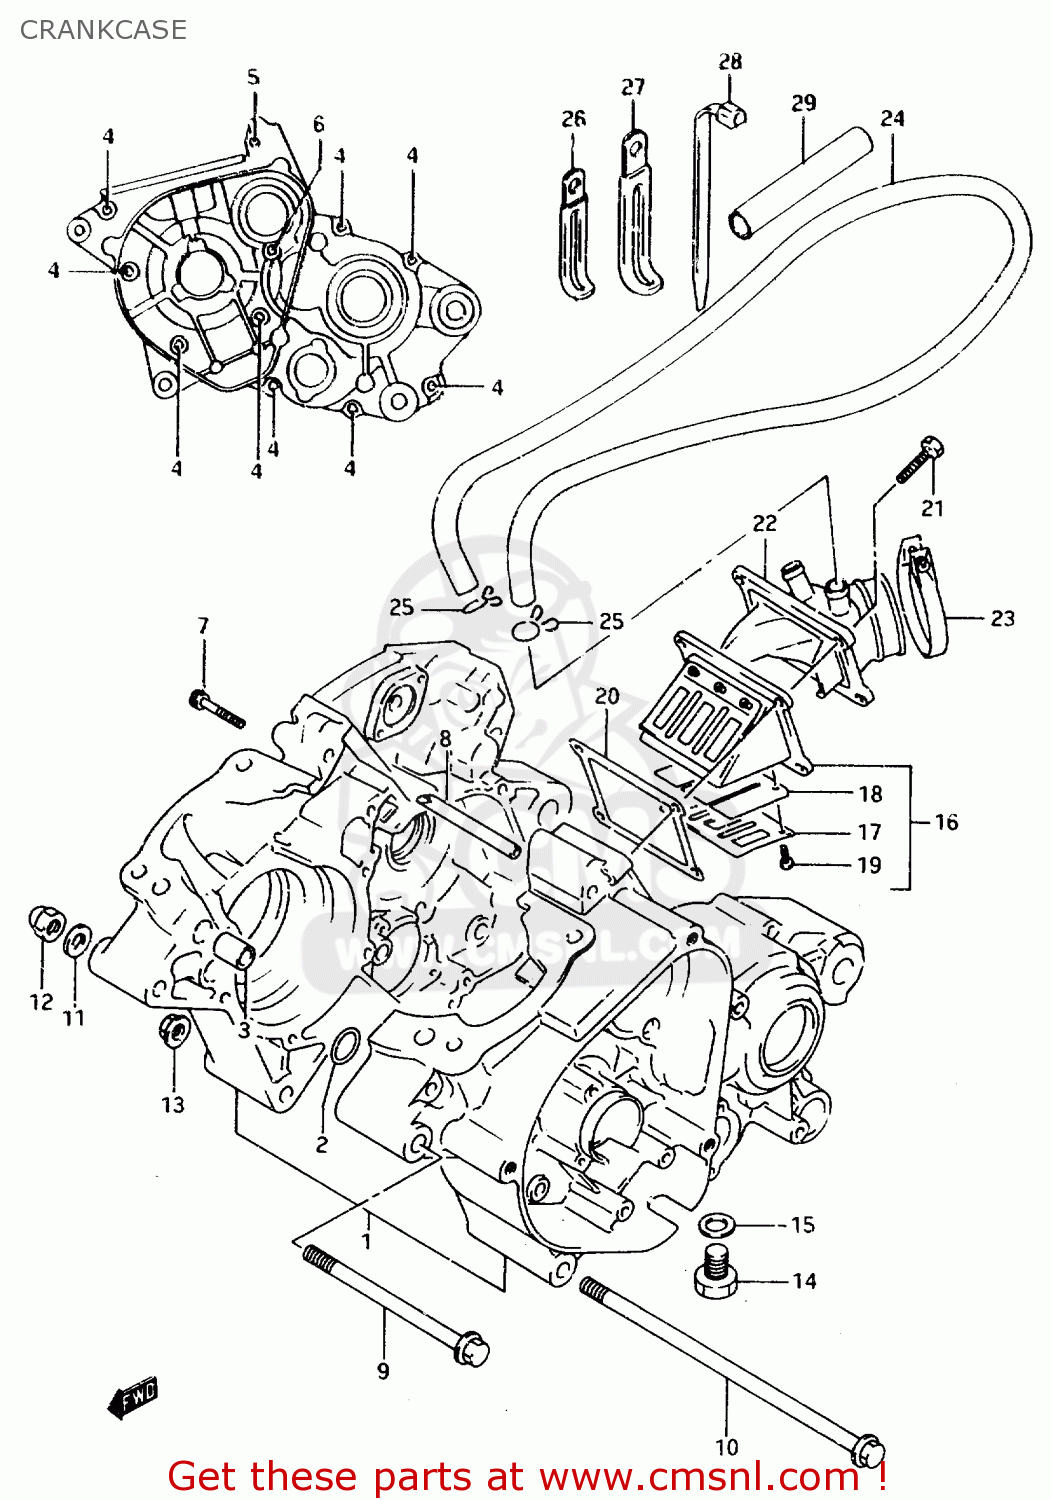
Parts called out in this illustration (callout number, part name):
1	CRANKCASE ASSY
2	O RING(D:1.9,ID:15.8)
3	PIN
4	BOLT
5	BOLT
6	SCREW,CRANKCASE
7	BOLT
8	PIPE,BREATHER
9	BOLT(8X115)
10	BOLT(8X205)
11	WASHER (8.5X16X2.6)
12	NUT
13	NUT
14	PLUG
15	GASKET(13.8X18.8X4.8) (NAS)
16	VALVE ASSY,REED
17	STOPPER,REED VALVE
18	VALVE,REED
19	SCREW,REED VALVE
20	GASKET, REED VALVE (NA)
21	BOLT
22	PIPE,INTAKE
23	CLAMP
24	HOSE, INTERFERENCE
25	CLIP
26	CLAMP
27	CLAMP
28	CLAMP(L:165)
29	TUBE,FUEL HOSE
